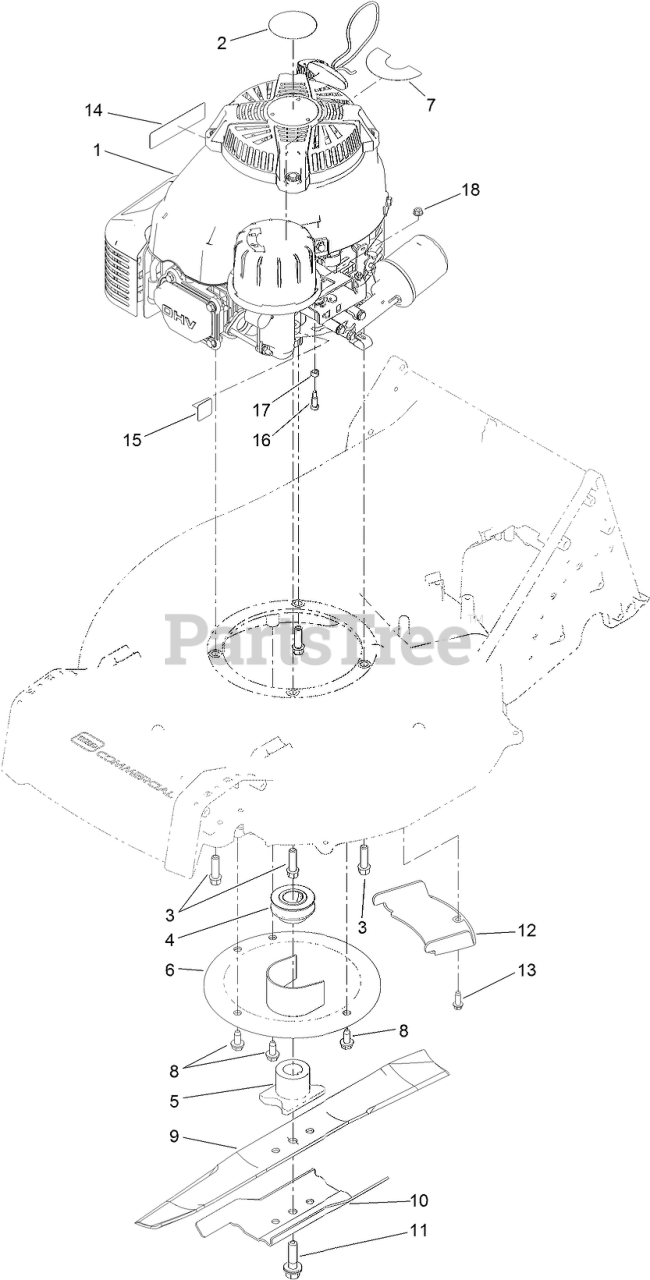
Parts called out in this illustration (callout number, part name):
1	ENGINE-KAWASAKI, FJ180V
3	SCREW-TAPTITE
4	PULLEY-DRIVER
5	DRIVER-BLADE
6	PROTECTOR-CRANKSHAFT
8	SCREW-HWHTF
9	BLADE-RECYCLING
10	ACCELERATOR-BLADE
11	BOLT-BLADE
12	COVER-BELT
13	SCREW-HWHTF
14	DECAL-ARRESTER, SPARK
15	DECAL-PRIMER
16	SCREW-SHOULDER
17	SPACER
18	NUT-LOCK, FLANGE
